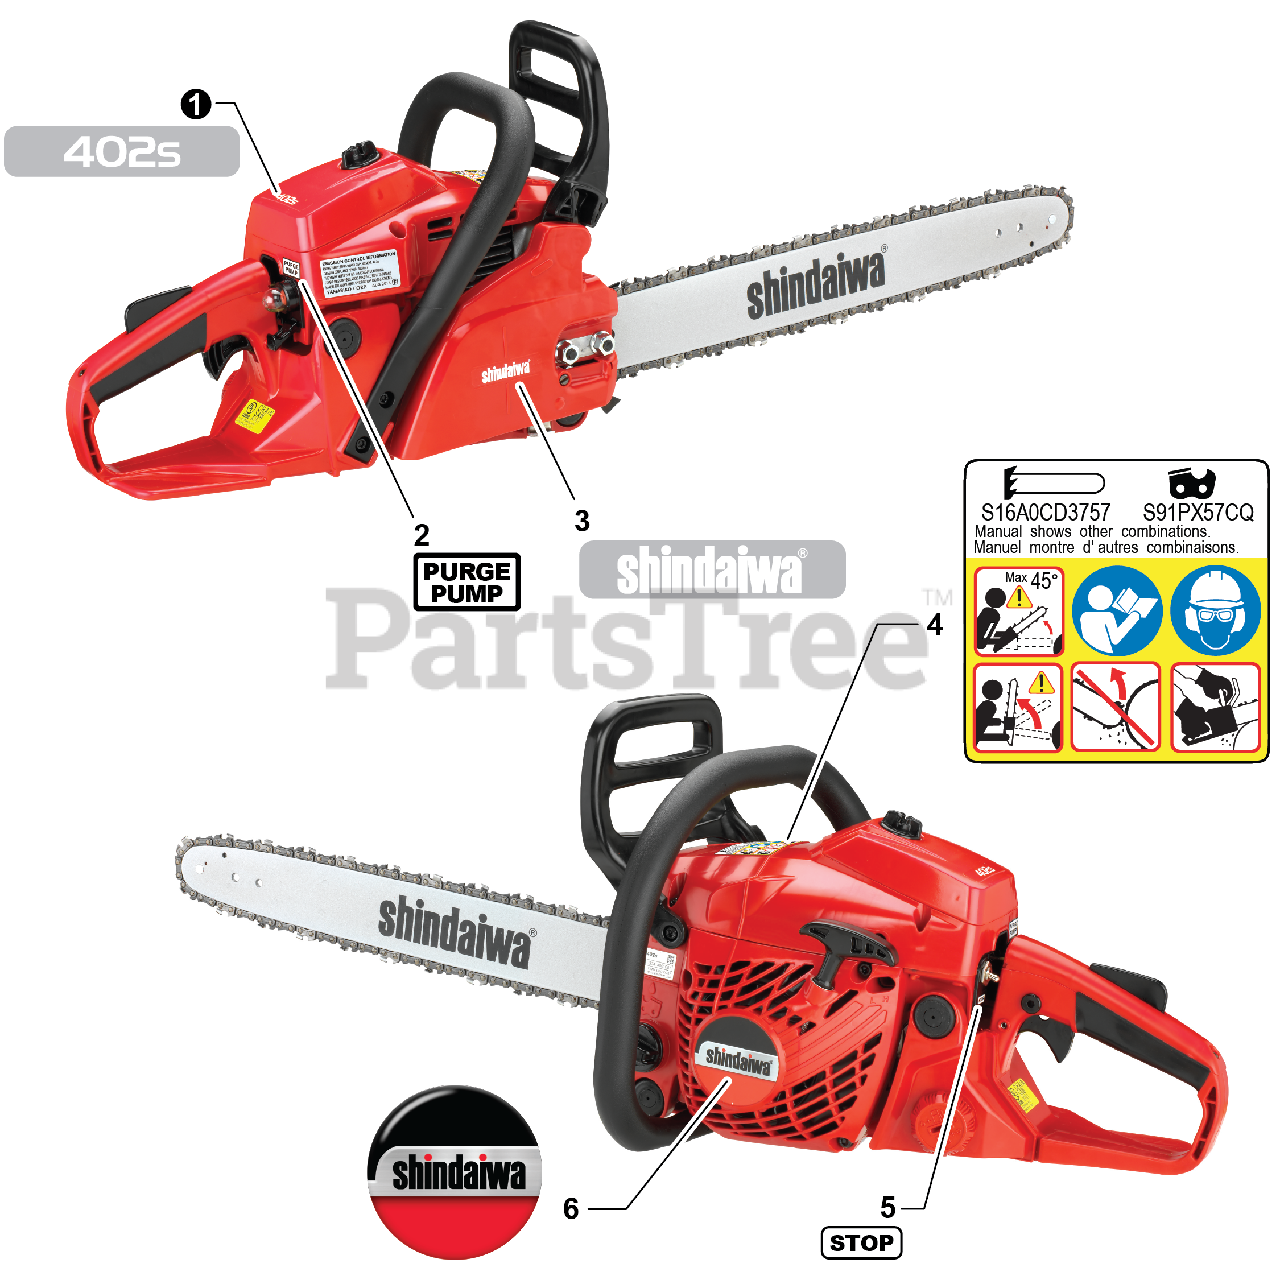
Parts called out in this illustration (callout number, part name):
1	LABEL - MODEL 402S
2	LABEL, PURGE PUMP
3	LABEL - SHINDAIWA
4	LABEL, CAUTION
5	LABEL, STOP
6	LABEL, STARTER - SHINDAIWA
